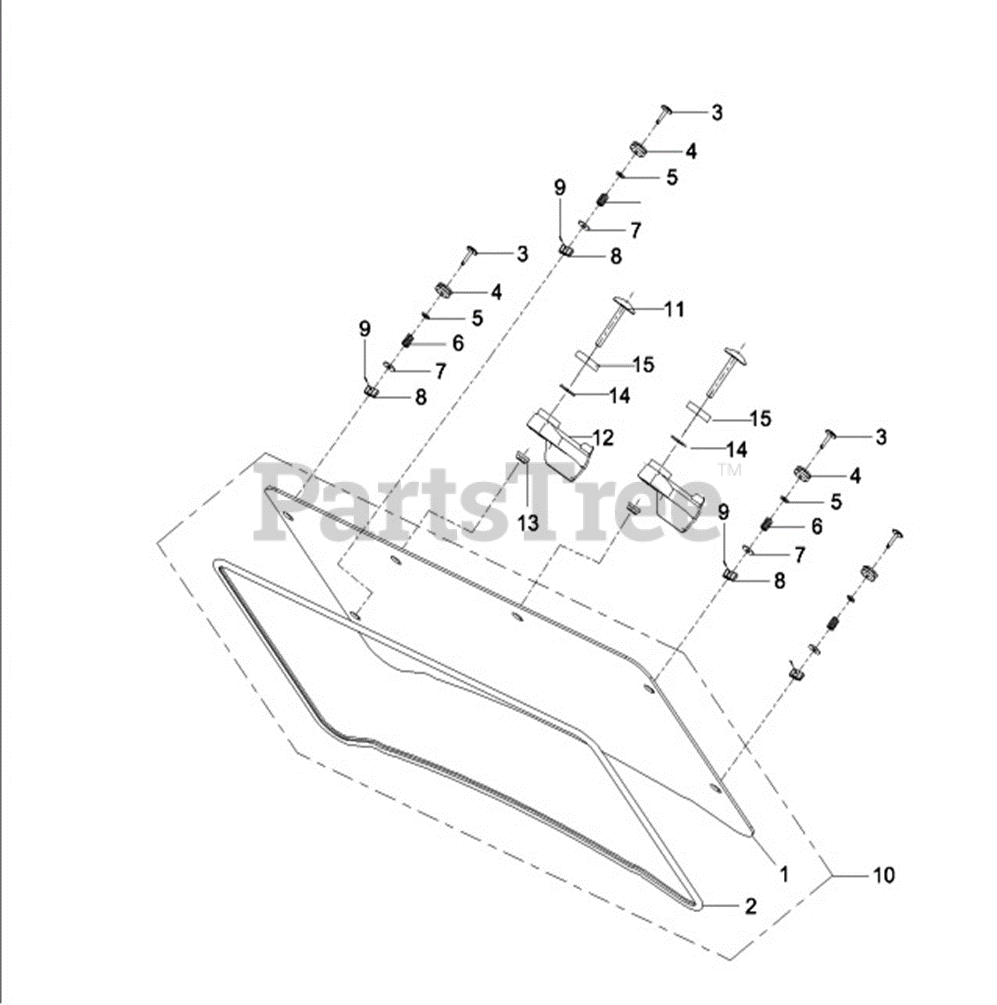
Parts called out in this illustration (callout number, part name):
1	FRONT WINDSHIELD
2	WINDSHIELD SEAL
3	LOCK PIN - WINDSHIELD
4	RUBBER WASHER M6X6.4
5	FLAT WASHER
6	PRESSURE SPRING
7	FLAT WASHER 6X25X2
8	HAND SHANK LOCK
9	PIN SPRING 3.4X10
10	FRONT WINDSHIELD ASSEMBLY
11	WINDSHIELD LEVER PIN
12	WINDSHIELD LEVER
13	LOCK NUT M6
15	FLAT WASHER 5.7x 26 x 2.5
